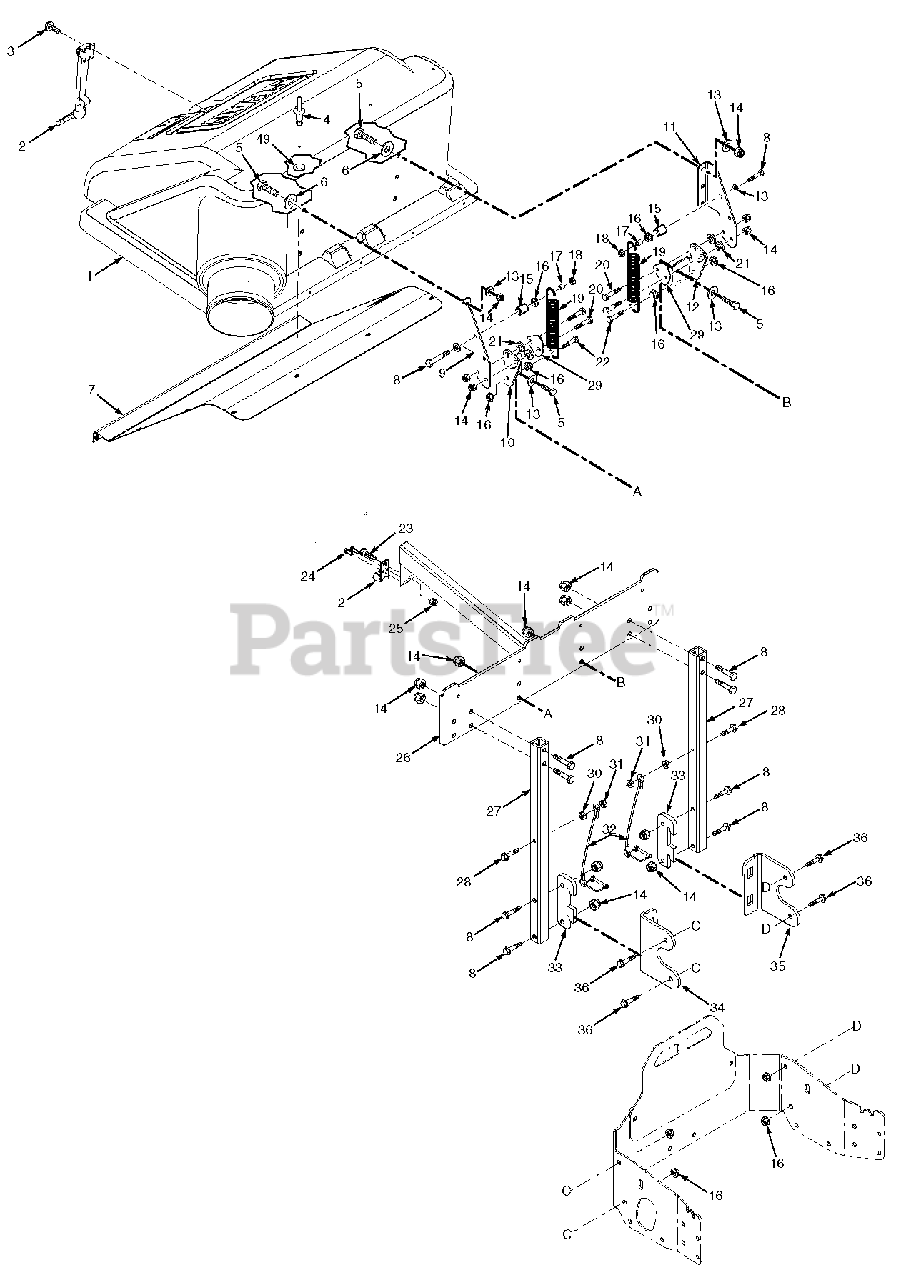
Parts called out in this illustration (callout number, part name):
1	Hood Assembly
2	Latch
3	Screw, #10-32 x 3/4"
3	Flatwasher, 3/8-.193 x .496 x .048
3	Nut, Elastic Stop #10-32
4	Pop Rivet, 3/16 x .652
5	Bolt, Hex Head 3/8-16 x 1-1/4"
6	Flatwasher, 3/8-.406 x 1.5 x 7 Ga.
7	Screen, GC Hood
8	Bolt, Hex Head 3/8-16 x 2-1/4"
9	Hinge, Upper RH
10	Hinge, Lower RH
11	Hinge, Upper LH
12	Hinge, Lower LH
13	Flatwasher, 3/8-391 x .938 x .105
14	Nut, Elastic Stop 3/8-16
15	Spacer
16	Nut, Serrated Flange 3/8-16
17	Sleeve
18	Nut, Center Lock 3/8-16
19	Spring
20	Bolt, Hex Head 3/8-16 x 1-1/2"
21	Bushing, Hopper Pivot
22	Bolt, Hex Head 3/8-16 x 1-3/4"
23	Bolt, Hex Head 5/16-18 x 3/4"
24	Pop Rivet, 3/16 x .402
25	Nut, Elastic Stop 5/16-18
26	Frame Weldment, Bag Support
27	Tube, Grass Catcher Mount
28	Bolt, Hex Head 1/4-20 x 2"
29	Guard, Hinge
30	Nut, Serrated Flange 1/4-20
31	Nut, Center Lock 1/4-20
32	Snap Pin Assembly
33	Latch, GC
34	Bracket, GC Mount RH
35	Bracket, GC Mount LH
36	Bolt, Hex Head 3/8-16 x 1"
37	Flatwasher, 3/16-.196 x .469 x .048
